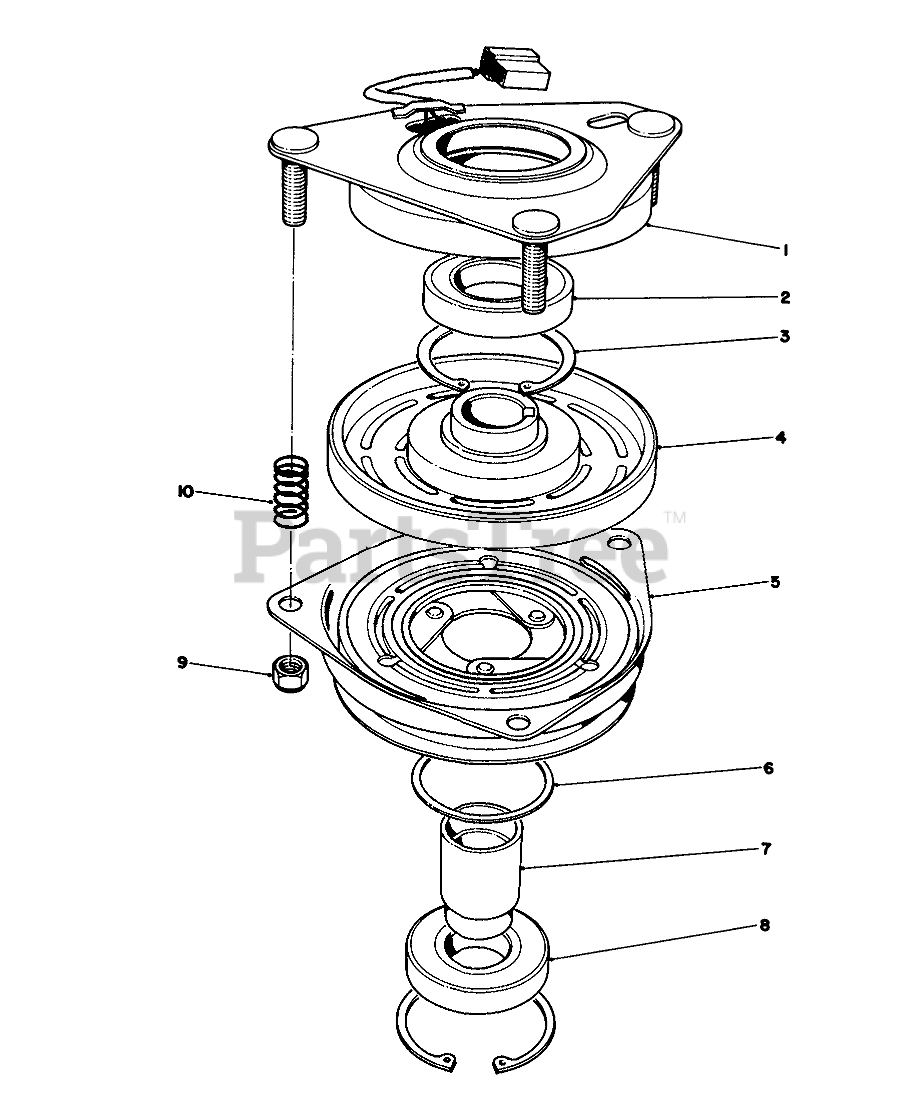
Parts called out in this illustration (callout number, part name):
1	Field Assy. (Incl. Ref. #2 & 3)
2	BEARING-FIELD
3	RING-RETAINING
4	Field Coil, Rotor & Bearing Assembly (Incl. Ref. #1)
5	Armature & Pulley Assembly (Incl. Ref. #3, 6, 7 & 8)
6	SPACER-BEARING, PULLEY
7	COLLAR-BEARING
8	BEARING-PULLEY
9	NUT-HEX
10	SPRING
